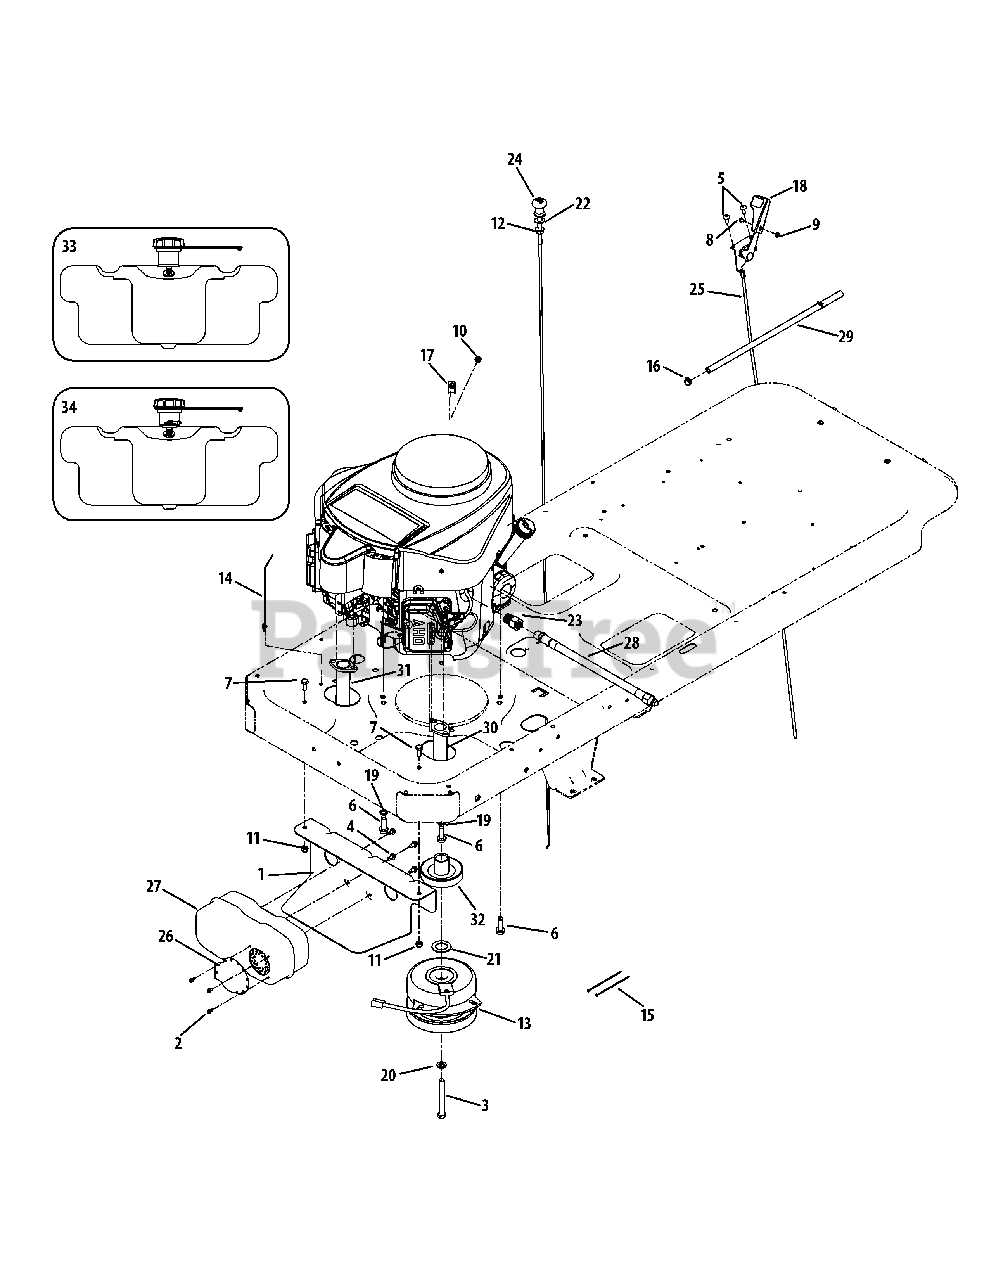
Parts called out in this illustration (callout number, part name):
1	Muffler Mounting Bracket
2	Hex Washer Head Screw, #8-18 x .5
3	Hex Cap Lock Screw, 7.16-20 x 3.5
4	Hex Washer Head Screw, 1.4-20 x .5
5	AB Screw, 1.4-14 x .625
6	Hex Washer Hd. Screw, 3.8-16 x 1.25
7	Hex Cap Screw, 5.16-18 x .75
8	Truss Hd. Mach. Screw, #8-32 x .375
9	Hex Nut, #8-32
10	Sems Nut, 1.4-20
11	Hex Lock Nut, 5/16-18
12	Flange Lock Nut, 3/8-16
13	Electric PTO Clutch
14	Cable Tie
15	Cable Tie
16	Hose Clamp
18	Throttle Control Knob
19	Lock Washer, 3/8
20	Lock Washer, 7/16
21	Flat Washer, 1.031 x 1.620 x .095
22	Flat Washer, .406 x .875 x .059
23	Hex Fitting
24	Choke Cable
25	Throttle Cable
26	Muffler Deflector
27	Dual Inlet Muffler
28	Oil Drain Hose
30	RH Exhaust Pipe
31	LH Exhaust Pipe
32	Electric PTO Engine Pulley
33	Fuel Tank Assembly
33	Fuel Tank Bushing
33	Fuel Pick-Up Bushing
33	Fuel Tank
33	Fuel Cap
34	Fuel Tank Assembly
34	Fuel Tank Bushing
34	Rubber Grommet
34	Rollover Valve Grommet
34	Fuel Pick-Up Fitting
